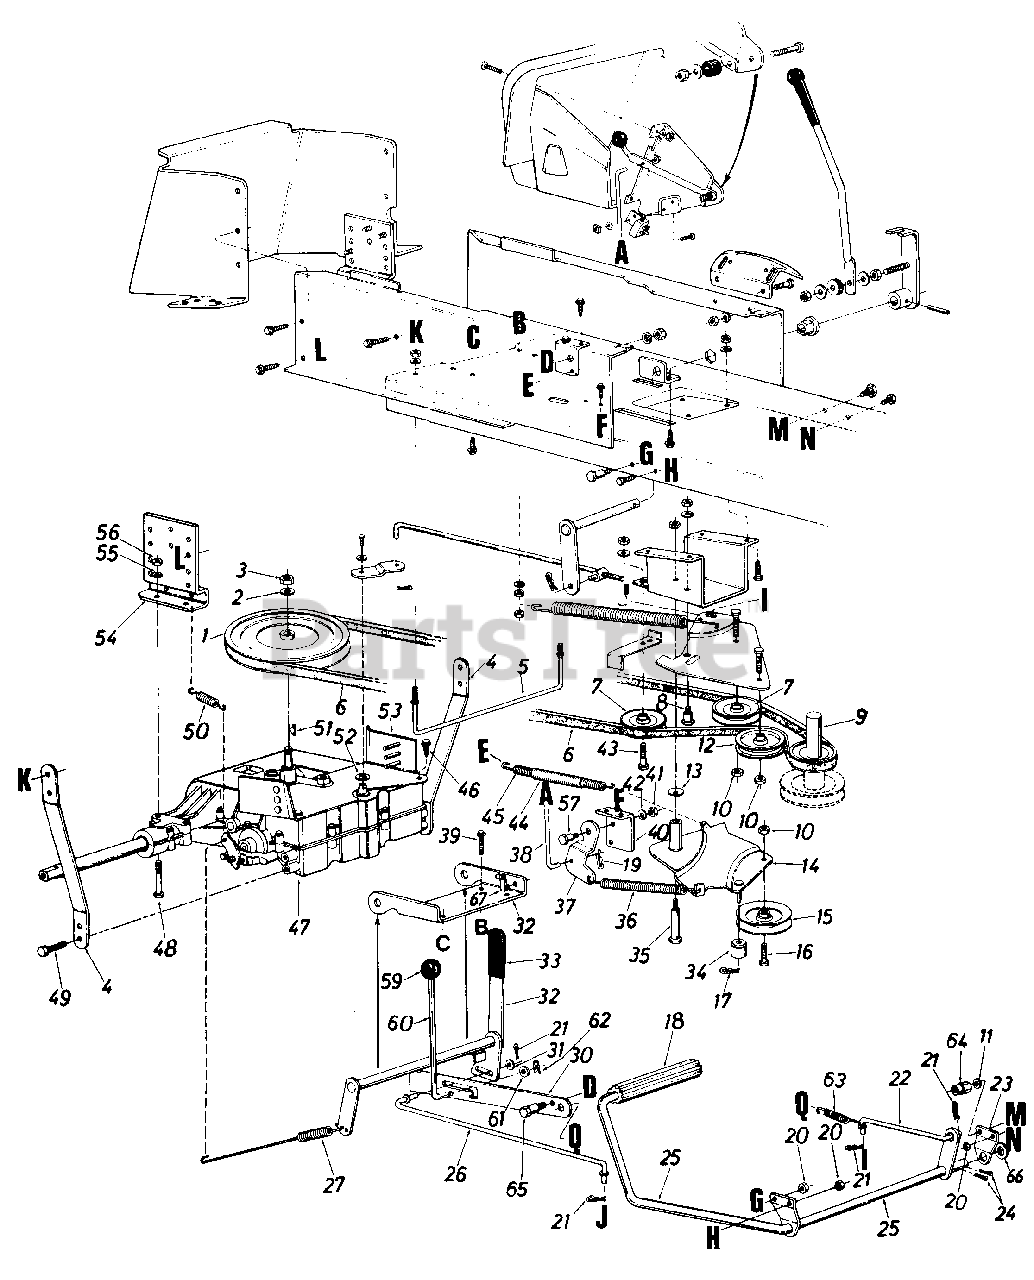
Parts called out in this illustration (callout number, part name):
1	8" "V"-Pulley
2	L-Wash. 1/2" I.D.
3	Hex Nut 1/2-20 Thd.
4	Transaxle Brace
5	Belt Guard
6	"V"-Belt
7	"V"-Belt Idler Pulley .38" I.D. x 3-1/16" O.D.
8	Shoulder Bolt .435" Dia. x .160 (5/16-18)
9	Two Step Engine Pulley 3.10" & 5.56" Dia.
10	Hex Cent. L-Nut 3/8-24 Thd.
11	L-Wash. 3/8" I.D.
12	Flat Idler Pulley 2.75" O.D.
13	Belleville Wash. .400" I.D. x .88" O.D. x .063
14	Idler Bracket Ass'y.
15	4" "V"-Idler Pulley
16	Hex Bolt 3/8-24 x 1.5" Lg.
17	Hairpin Cotter 5/16" Dia.
18	Foot Pad
19	Intern. Cotter Pin 5/16" Dia.
20	Hex Cent. L-Nut 3/8-16 Thd.
21	Hairpin Cotter 3/32" Dia. x 3/4" Lg
22	Brake Clutch Rod (4.60" Lg.)
23	Clutch Rod Bearing Brkt.
24	Cotter Pin 1/8" Dia. x 1.00" Lg.*
25	Clutch Brake Pedal Ass'y.
26	Brake Cam Rod (13.60" Lg.)
27	Extension Spring .59" O.D. x.93" Lg.
30	Parking Brake Cam
31	Fl-Wash. .406" I.D. x 1.00" O.D. x .030 Thk.
32	Hand Brake Lever Ass'y.
33	Grip-Flat Bar 11/4" Wide
34	Spacer
35	Shoulder Bolt .496" Dia. x 2.00" Lg. (3/8-16)
36	Extension Spring .75" O.D. x 6.12" Lg.
37	Deck Control Brkt.
38	Deck Control Rod
39	Hex Wash. Hd. TT-Tap Scr. 1/4-20 x 1.50" Lg.
40	Parking Brake Cam Mtg. Brkt
41	Hex Nut 5/16-18 Thd.*
42	L-Wash. 5/16" I.D.*
43	Hex Bolt 3/8-24 x 1.50" Lg. (Grade 5)
44	Convoluted Conduit .50" I.D. x 4.0" Lg.
45	Ext. Spring .50" O.D. x 6.37" Lg.
46	Hex Wash. Hd. AB Tap Scr. 5/16-18 x 5/8" Lg.
47	Transaxle
48	Hex Bolt 5/16-18 x 2.50" Lg. *
49	Hex Wash. Hd. AB Tap Scr. 5/16-18 x 5/8" Lg.
50	Extension Spring .50" O.D. x 2.75" Lg.
51	Hi-Pro Key 3/32" x 5/8" Dia.
52	Special Wash. 1.00" O.D. (Hdn.)
53	Transaxle Belt Keeper Ass'y.
54	Transaxle Support Bracket
55	L-Wash. 5/16" I.D.*
56	Hex Nut 5/16-18 Thd.*
57	Shoulder Bolt .435" Dia. x .162" Lg. (5/16-18)
59	Ball Knob
60	Parking Brake Link
61	Fl-Wash.
62	Hairpin Cotter
63	Ext. Spring 3.12" Lg.
64	Spacer Nut 3/8-16 Thd.
65	Shld. Bolt .435" Dia. x .162" Lg.
66	Fl-Wash. .53" I.D. x .93" O.D.
67	Plastic Hose Clamp
